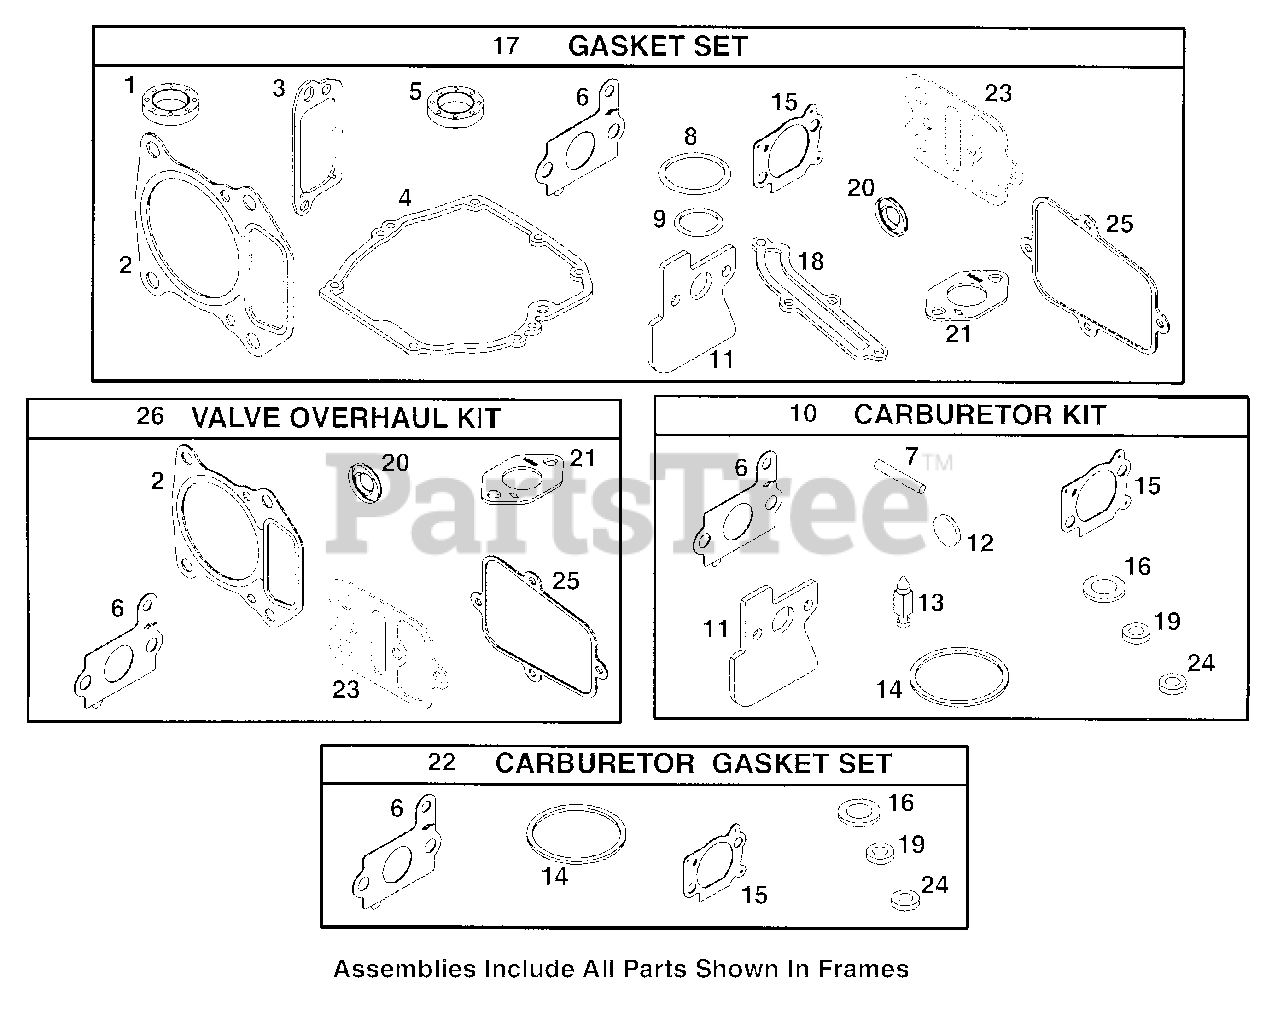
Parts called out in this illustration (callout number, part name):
1	Oil Seal
2	Cylinder Head Gasket
3	Breather Gasket
4	Crankcase Gasket
5	Oil Seal
6	Intake Gasket
7	Float Hinge Pin
8	Seal-O-Ring
9	Seal-O-Ring
10	Carburetor Kit
11	Carburetor Spacer
12	Welch Plug
13	Needle Valve
14	Float Bowl Gasket
15	Air Cleaner Gasket
16	Seal Washer
17	Gasket Set
18	Breather Passage Gasket
19	Choke Shaft Seal
20	Valve Seal
21	Exhaust Gasket
22	Carb. Gasket Set
23	Throttle Shaft Gasket Seal
24	Throttle Shaft Seal
25	Rocker Cover Gasket
26	Valve Overhaul Kit
